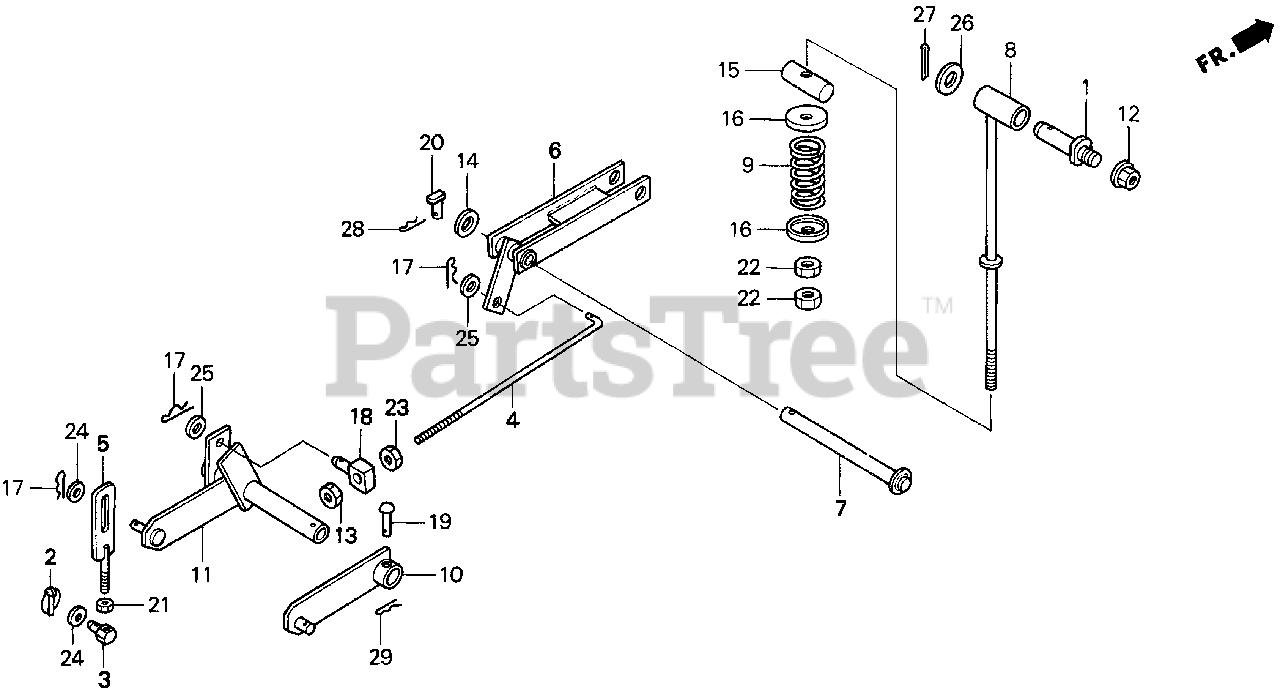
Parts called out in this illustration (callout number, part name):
1	PIN, LIFT ARM
2	LINCHPIN ASSY.
3	PIN, FR. LINK ADJUSTING
4	ROD, CUTTER DECK LIFT
5	PLATE, CUTTER DECK LIFT
6	LINK, CUTTER DECK LIFT
7	SHAFT, LIFT LINK
8	ROD, LIFT LINK
9	SPRING, LIFT DAMPER
10	ARM, R. LIFT
11	ARM, L. LIFT
12	NUT, SPECIAL (16MM)
13	NUT, SELF-LOCK (16MM)
14	WASHER, PLAIN (22MM)
15	PIN, DAMPER SPRING
16	WASHER (16MM)
17	PIN, LOCK (14MM)
18	PIN, LIFT ARM
19	PIN, LIFT ARM (10X51.5)
20	PIN, LINK SHAFT (8X28)
21	NUT, HEX. (12MM)
22	NUT, HEX. (16MM)
23	NUT, HEX. (16MM)
24	WASHER, FLAT (14MM)
25	WASHER, FLAT (16MM)
26	WASHER, FLAT (18MM)
27	PIN, COTTER (3.0X35)
28	PIN, LOCK (8MM)
29	PIN, LOCK (10MM)
